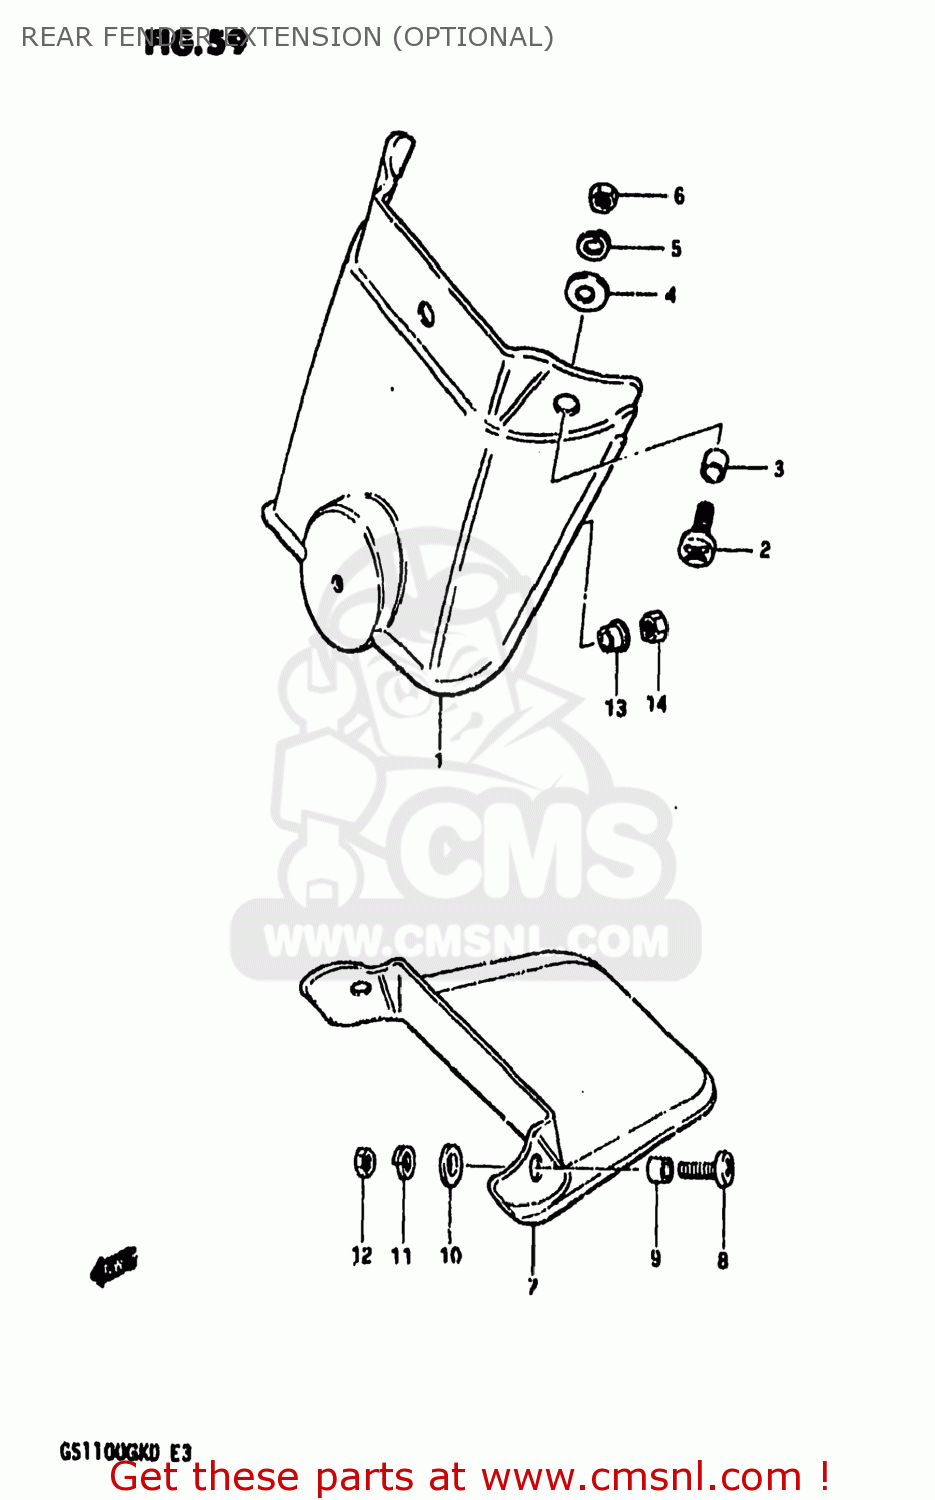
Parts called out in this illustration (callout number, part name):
1	EXTENSION,REAR FENDER
2	SCREW (6X15)
3	SPACER(6.2X8.3X5.7)
4	WASHER(6.5X18X1)
5	LOCK WASHER
6	NUT
7	EXTENSION,REAR FENDER
8	SCREW (6X15)
9	SPACER(6.2X8.3X5.7)
10	WASHER(6.5X18X1)
11	LOCK WASHER
12	NUT
13	SPACER
14	NUT
